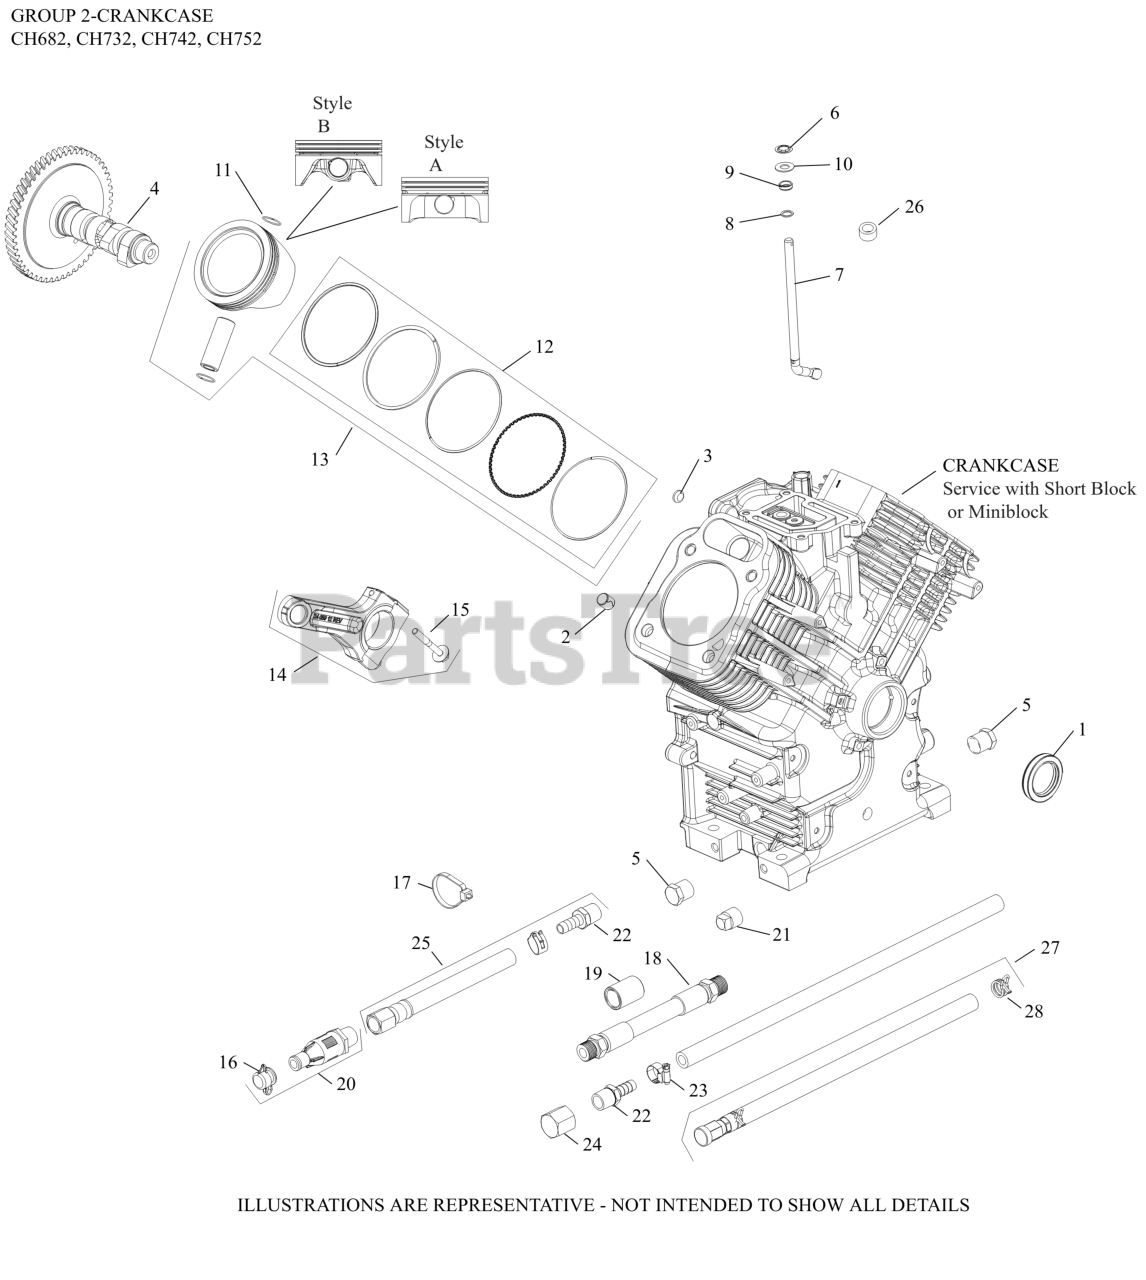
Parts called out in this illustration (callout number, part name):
1	SEAL, OIL (HELIX LIP)
2	PIN, LOCATING
3	PLUG, CUP
4	KIT, CAMSHAFT
5	PLUG, HD PIPE 3/8"
6	RETAINER, RING
7	SHAFT, GOVERNOR CROSS
8	WASHER, FLAT 11/32"
9	SEAL, GOVERNOR CROSS SHAFT
10	WASHER, FLAT 9 MM
11	RETAINER, PISTON PIN
12	RING DISC USE PISTON ASSY PER SPEC
12	RING SET(.08)STYLE A-1.5mm Tp RING THICK
12	RING SET(.25)STYLE A-1.5mm Tp RING THICK
12	RING SET(.50)STYLE A-1.5mm Tp-(#DSC)
12	RING SET(STD)STYLE B-1.2mm Tp RING THICK
12	RING SET(.08)STYLE B-1.2mm RING THICK
12	RING SET(.25)STYLE B-1.2mm Tp RING THICK
12	RING SET(.50)STYLE B-1.2mm Tp RING THICK
13	KIT,PSTN/RNG STYLE A(STD)(#2587406S)
13	KIT,PSTN/RNG STYLE A(.08)
13	KIT,PSTN/RNG STYLE A(.25)USE 2587411-S
13	KIT,PSTN/RNG STYLE A(.50)(#2587404S)
13	KIT,PSTN/RNG STYLE B(STD)
13	KIT,PSTN/RNG STYLE B(.08)
13	KIT,PSTN/RNG STYLE B(.25)
13	KIT,PSTN/RNG STYLE B(.50)
14	ROD, ASSEMBLY CONNECTING
15	KIT, ROD BOLTS-(#25086677S)
